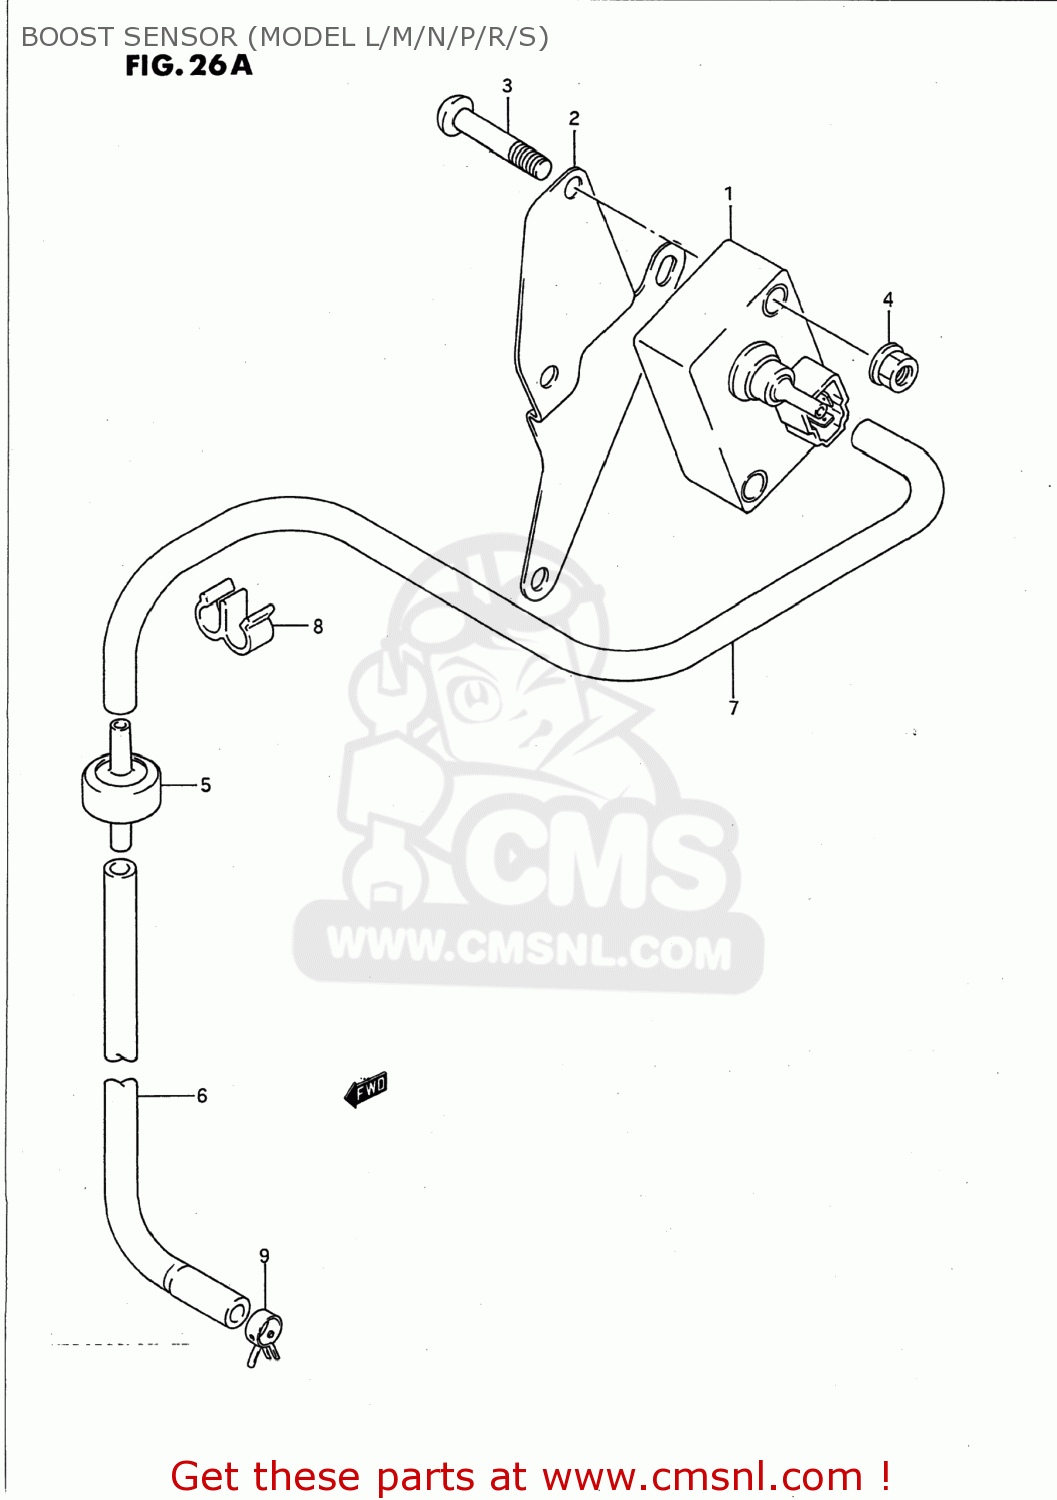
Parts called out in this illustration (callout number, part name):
1	SENSOR ASSY,BOOST
2	BRACKET,BOOST SENSOR
3	SCREW,6X30
4	NUT
5	FILTER,VSV
6	HOSE,BOOST NO.1
7	HOSE (3.5X7.5X2000)
8	CLAMP
9	CLAMP
